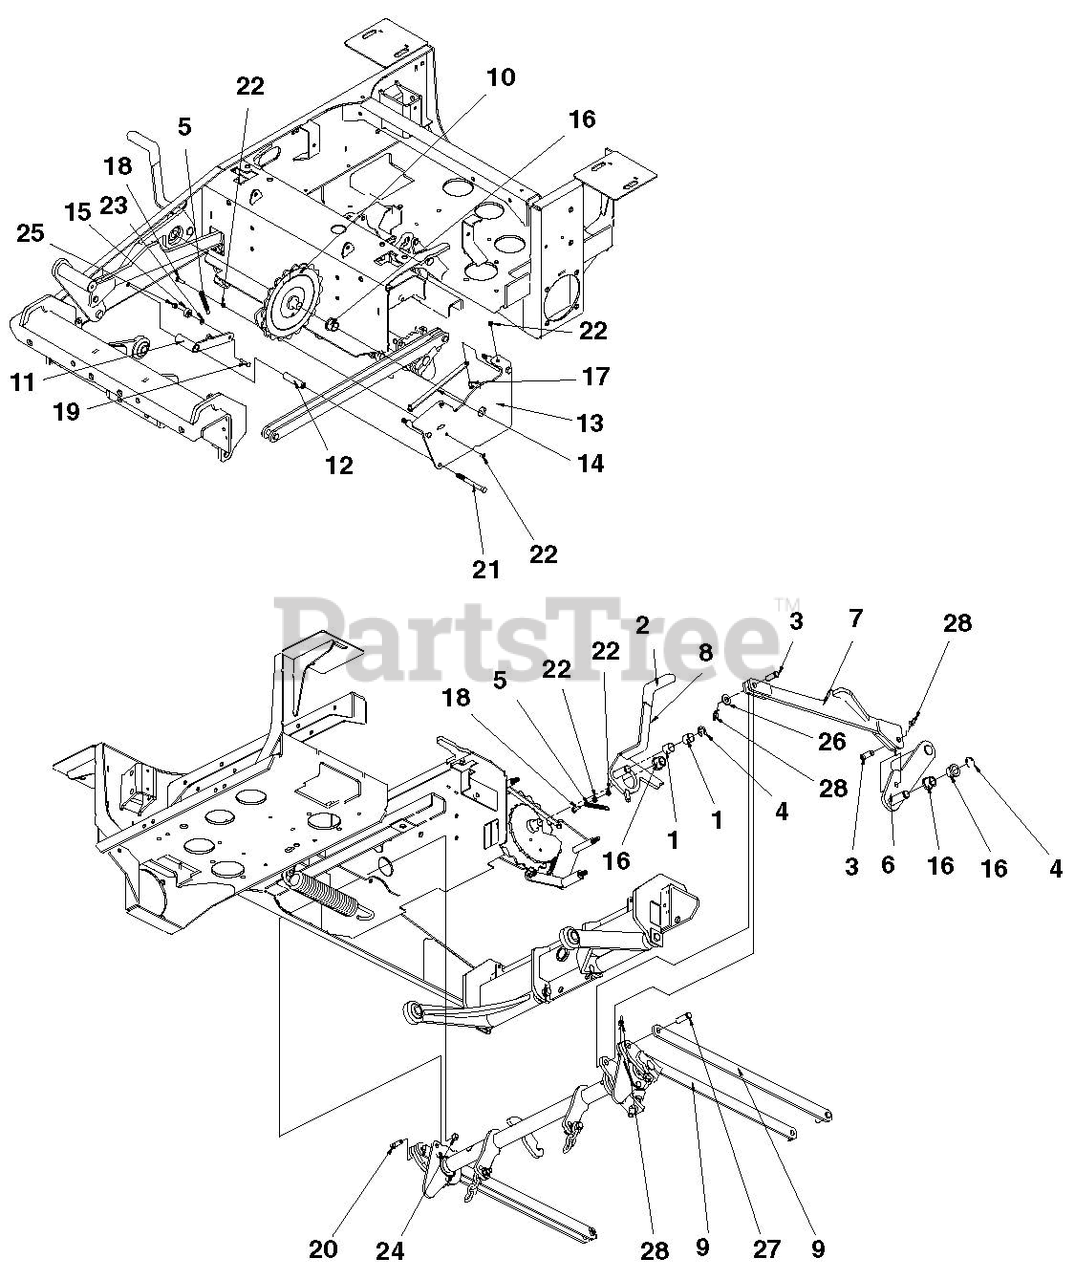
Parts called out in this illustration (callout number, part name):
1	BRG, SLV .753X.878X.750
2	GRIP, RUBBER LEVER
3	PIN, CVS .500X1.25X1.02 Y
4	E-RING, .750 X .050 Y
5	SPRING, EXT .375X.055X2.25 Y
6	WLDT, FOOT ARM
7	WLDT, FOOT CONNECTOR
8	WLDT, TRANSPORTATION LOCK
9	PLATE, CONNECTOR LINK
10	ASSY, CAM CONTROL W/DECALS S/O
11	WLDT, ARM
12	TUBE, RD .625 X .120 X 2.53 Y
13	PLATE, HOC INDICATOR
14	PLATE, FINGER GUARD
15	BRG, BAL .250X.688X.313
16	BUSHING, .750 X 1.00 X .750
17	BOLT, 1/4-20X.500 HEX 5 Y
18	BOLT, 1/4-20X.750 HEX 5 Y
19	BOLT, 1/4-20X1.00 HEX 5 Y
20	BOLT, 3/8-16X1.00 HEX 5 Y
21	BOLT, 3/8-16X3.50 HEX 5 Y
22	NUT, 1/4-20 STD HEX GR5 Y
23	WASHER, M6 REG FLAT Y
24	LOCKNUT, 3/8-16 CROWN Y
25	LOCKNUT, 1/4-20 NYLOC Y
26	WASHER, .500X1.00X.105 FLAT Y
27	PIN, CVS .500X1.50X1.27 Y
28	RING, RUE .500 X .062 X 1.420
